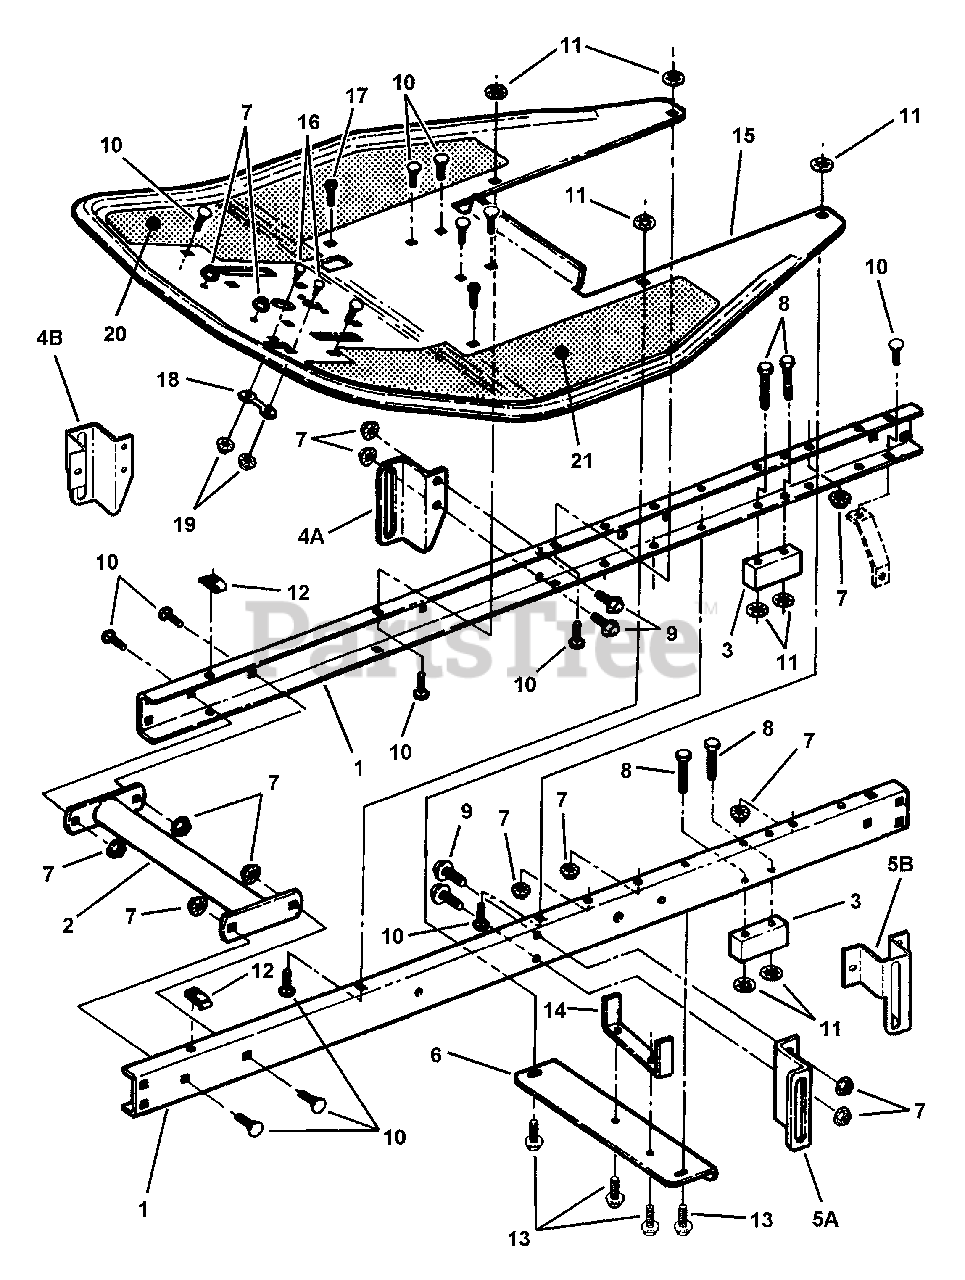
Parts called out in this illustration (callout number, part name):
1	FRAME RAIL, L.H. & R.H.
2	WELDMENT, Frame Reinforcement Tube
3	SPACER BLOCK, Hydro
4A	GUIDE, Deck R.H.
4B	GUIDE, Deck R.H.
5A	GUIDE, Deck L.H.
5B	GUIDE, Deck R.H.
6	CHANNEL, Belt Finger
7	NUT, 5/16-18 Hex Flange Lock, Grade 5
8	SCREW, 5/16-18 x 3-3/4" Hex Head Cap
9	BOLT, 5/16-18 x 5/8" Hex Flange Lock, Grade 5
10	BOLT, 5/16-18 x 3/4" Short Neck Carriage, Grade 5
11	RETAINER, 5/16" Bolt
12	NUT, 5/16" Push On
13	SCREW, 1/4-20 x 3/8" Hex Washer Self-Tap
14	BELT GUIDE, Rear
15	FLOOR PAN
16	BOLT, #10-24 x 1/2" Short Neck Carriage, Grade 2
17	SCREW, 5/16-18 x 7/8" Truss Head Torx
18	STOP, Park Brake
19	NUT, #10-24 Hex Flange Lock
20	FLOOR MAT - R.H.
21	FLOOR MAT - L.H.
